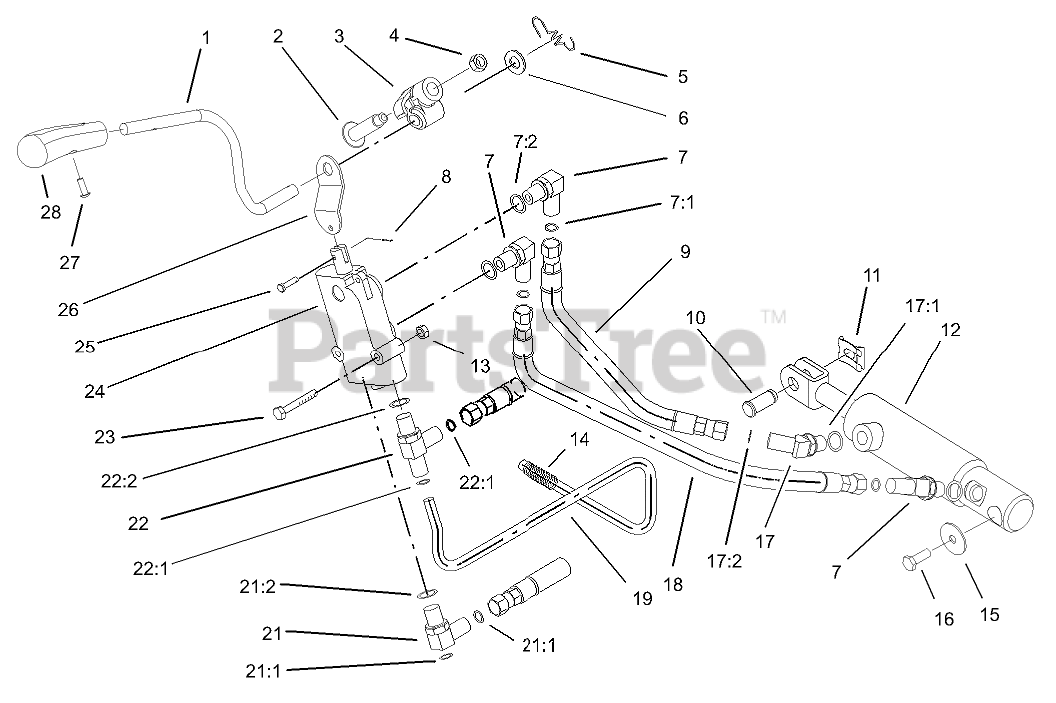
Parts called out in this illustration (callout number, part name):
1	HANDLE-LIFT
2	BOLT-SHOULDER
3	TRUNNION-LEVER, LIFT
4	NUT-JAM, LOCKING
5	SPRING-EXTENSION, LIFT
6	WASHER
7	FITTING-HYD, 90 DEGREE
7:1	O-RING
7:2	O-RING
8	PIN-COTTER
9	HOSE ASM
10	PIN-CLEVIS
11	CLIP-PIN
12	LIFT CYLINDER ASM
13	NUT-LOCK, NI
14	COVER-BRACE
15	WASHER-FLAT
16	SCREW-THREAD LOCKING
17	FITTING-HYD, 45 DEGREE
17:1	O-RING
17:2	O-RING
18	HOSE ASM
19	TUBE-HYD
21	FITTING-HYD, 90 DEGREE
21:1	O-RING
21:2	O-RING
22	FITTING-HYD, TEE
22:1	O-RING
22:2	O-RING
23	SCREW-HH
24	VALVE-HYD
25	PIN-CLEVIS
26	LINK-LIFT
27	SCREW-PPHTF
28	KNOB - LIFT
